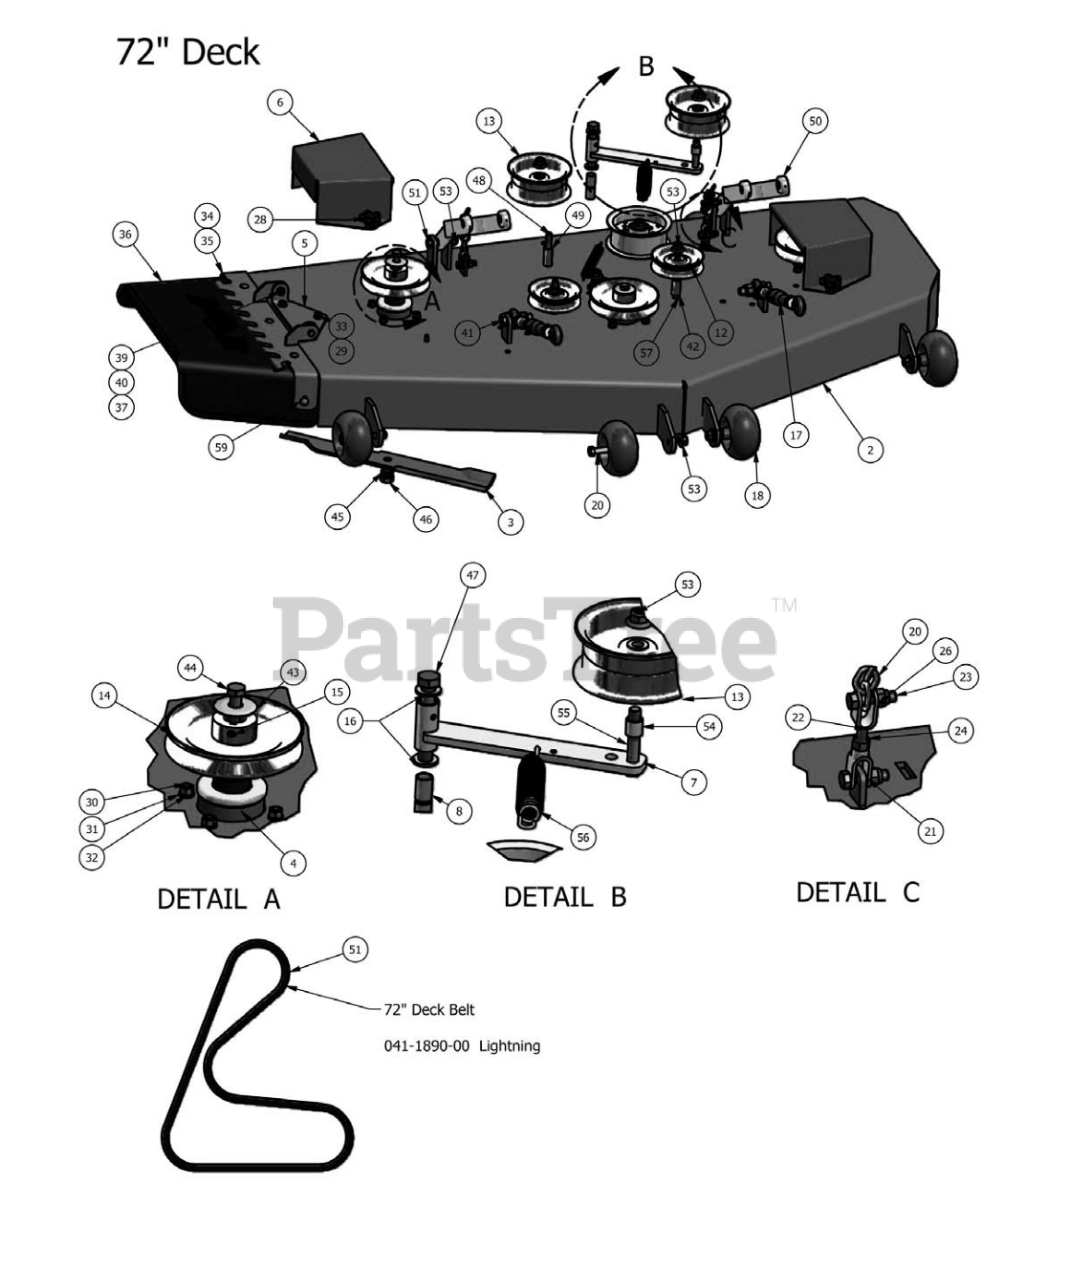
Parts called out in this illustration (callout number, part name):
1	72" Deck Complete Assembly with Spindles
2	72" Deck Shell Only
3	72" Inch Fusion Blade
4	Double Bearing Spindle Assembly
5	Discharge Chute Hanger
6	Plastic Pulley Cover
7	Deck Idler
8	5/8 x 1 1/8" Brass Bushing
9	1/2" x 3" Hex Bolt
11	1/2-13 Nylon Flange Nut-Orange
12	4 3/4" Idler Pulley
13	5 3/4" Deck Idler Pulley
14	7" Drive Pulley
15	5/16" Set Screw
16	.635 ID Plastic Washer
17	Turnbuckle (Top Link)
18	Anti-Scalp Rollers
19	Anti-Scalp Rollers Complete Assembly
20	1/2" x 4" Bolt (Grade 8)
21	Female Yoke
23	3/8" x 1 1/2" Hex Bolt
24	3/8" Hex Nut
25	4" Chain Assembly
26	3/8 Nylock Nut
28	5/16" Knob
29	3/8" x 3/4" Hex Bolt.
30	3/8" x 1 1/4" Hex Bolt
31	3/8" Lock Washer
32	3/8" Hex Nut
33	3/8" Flange Nut
34	72" Lower Hanger
35	72" Discharge Chute Upper Hanger Plate
36	Rubber Discharge Chute (Rubber Only)
37	.360 ID Plastic Washer
38	Complete Assembly Rubber Discharge Chute
39	5/16" x 1" Hex Bolt
40	5/16" Nylock Flange Nut
41	5/8" x 2 1/2" Hex Bolt
42	Pulley Spacer
43	Cup Washer
44	1/2" x 1 1/2" Hex Bolt
45	5/8" Lock Washer
46	5/8-18 x 1 1/2 GR 8 Hex Bolt
47	5/8" x 4" Hex Bolt
48	1/2-13 x 3 1/2 GR 5 Hex Bolt
49	1 3/4" Pulley Spacer
50	Deck Arm Assembly
51	1/2" x 2 1/2" Hex Bolt
52	1/2" Flange Nut
53	1/2-13 Nylon Flange Nut-Orange
54	3/4 OD x 1/2 ID x 3\4 Length
55	1/2 x 3" Bolt
56	Deck Idler Spring
57	1/2 x 3 1/2 Flange Bolt Grade 8
58	Deck Belt Lightning
59	5/16" x 1 1/4" Carriage Bolt
